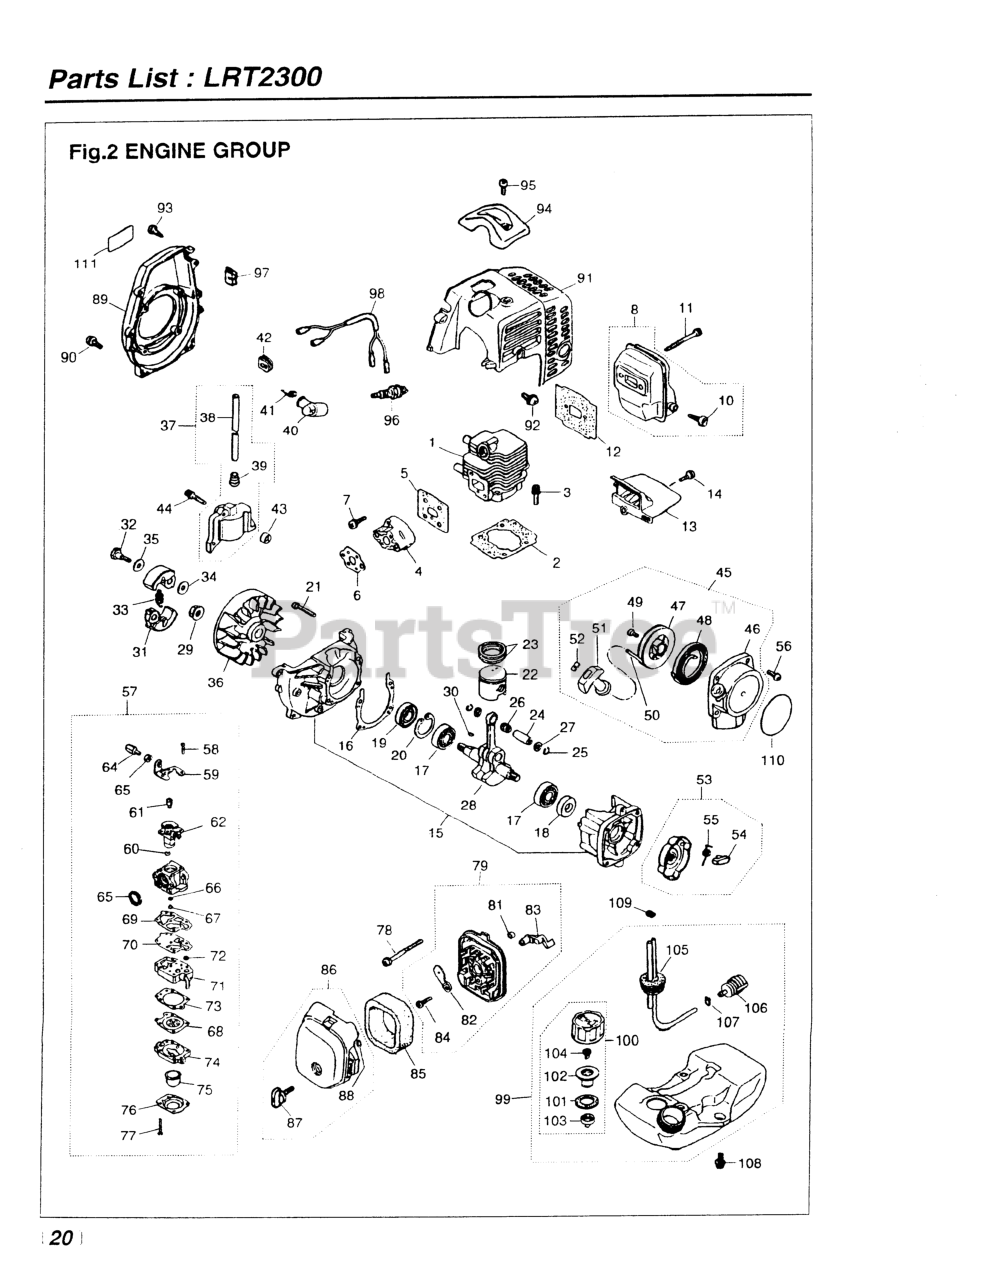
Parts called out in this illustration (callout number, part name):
1	CYLINDER
3	BOLT, M5 X 22
5	GASKET (RPLS -13120)
6	GASKET (REPLACES -13130)
7	SCREW, M5X20 (RPLS.1400-75510)
8	MUFFLER ASSY (RPLS 5501- )
10	ARRESTER (RPLS 5850-15140)
11	BOLT, M5 x 50
12	GASKET, MUFFLER (RPLS -15111)
14	SCREW, M4 X 16
15	CRANKCASE
16	GASKET (RPLS -21140)
17	BEARING
18	SEAL, OIL (RPLS 1100-21210)
19	SEAL, OIL (RPLS 1140-21220)
20	RING, SNAP, M28 x 1.2
21	BOLT, M5 X 30
22	PISTON (REPLACES 1140-41110)
23	RING, PISTON (RPLS 1850-41210)
24	PIN, PISTON 5x8x26
25	RING, SNAP (RPLS 1101-41320)
27	WASHER
28	CRANKSHAFT (RPLS 1850-42000)
30	KEY
31	SHOE (RPLS 1100-51114)
32	BOLT
33	SPRING, CLUTCH (RPLS-51220)
34	WASHER, FLAT (USE 182303)
36	ROTOR
37	COIL ASSY (RPLS 5500-71200)
38	CORD
39	CAP
41	SPRING
42	GROMMET
43	SPACER (RPLS -71260)
44	BOLT
45	RECOIL ASSEMBLY
46	CASE
47	REEL
48	SPRING, SPIRAL
49	SCREW (RPLS -75150)
51	KNOB
52	PLATE, STOPPER
53	PULLEY ASSY (RPLS -75210)
54	RATCHET (RPLS 1850-75220)
55	SPRING, RETURN
56	SCREW, M4 X 16
57	CARBURETOR
58	SCREW
60	RING
61	SWIVEL
62	VALVE ASSY
64	NUT, CABLE ADJUSTER
65	RING, PACKING
66	RING, O
67	JET
68	DIAPHRAGM (USE 4810-81260)
69	GASKET, PUMP
70	DIAPHRAGM
71	BODY, PUMP
73	GASKET, DIAPHRAGM
74	BODY, PURGE
75	PUMP, PRIMING
76	COVER, PUMP
77	SCREW
78	SCREW, M5 x 60
79	BODY-A (RPLS -82101)
81	SLEEVE
82	PLATE, CHOKE (RPLS-82130)
83	LEVER, CHOKE
84	SCREW (REPLACES 50030272)
85	ELEMENT
87	KNOB (RPLS -82220)
88	RING
89	COVER, FAN (RPLS-31110)
90	SCREW, M5X20 (RPLS.1400-75510)
91	COVER, ENGINE (RPLS -32111)
92	SCREW, M5 x 12
93	SCREW, HOUSING
94	GUARD, PLUG
95	SCREW,M5 X 14 (RPLS 1400-15510
98	CORD COMP (RPLS -73200)
101	PACKING
103	HOLDER, CAP
104	VALVE (NLA WHEN OUT)
105	PIPE COMPLETE
106	FILTER (RPLS 1850-85300)
107	CLIP (REPLACES 2841-31280)
108	SCREW
109	CLIP
110	LABEL, RECOIL
NI	SCREW, CABLE ADJUSTER
